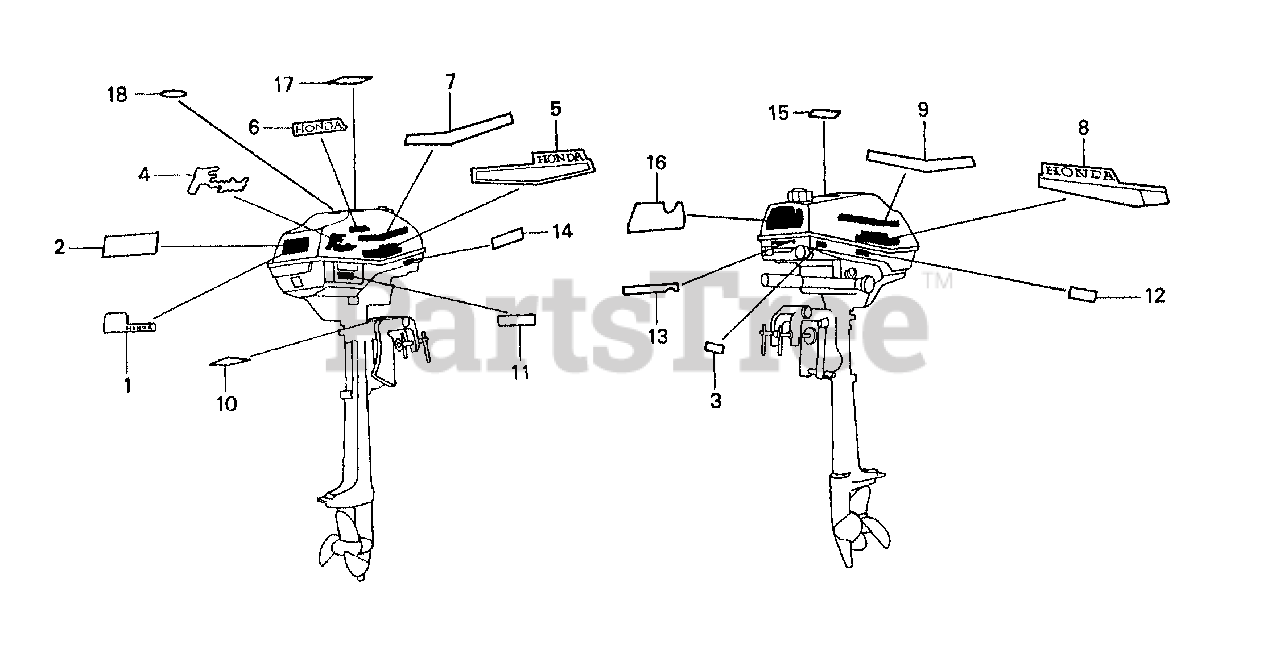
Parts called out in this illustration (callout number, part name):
2	EMBLEM, RR.
5	STRIPE, R. SIDE COVER
8	STRIPE, L. SIDE COVER
11	MARK, FUEL VALVE (E)
12	MARK, OIL CAUTION (E)
13	MARK, INDICATION (E)
14	CAUTION, STORING (E)
15	LABEL, RECOIL CAUTION (E,F)
16	LABEL, OPERATOR CAUTION (E)
17	MARK, TANK CAUTION (E)
